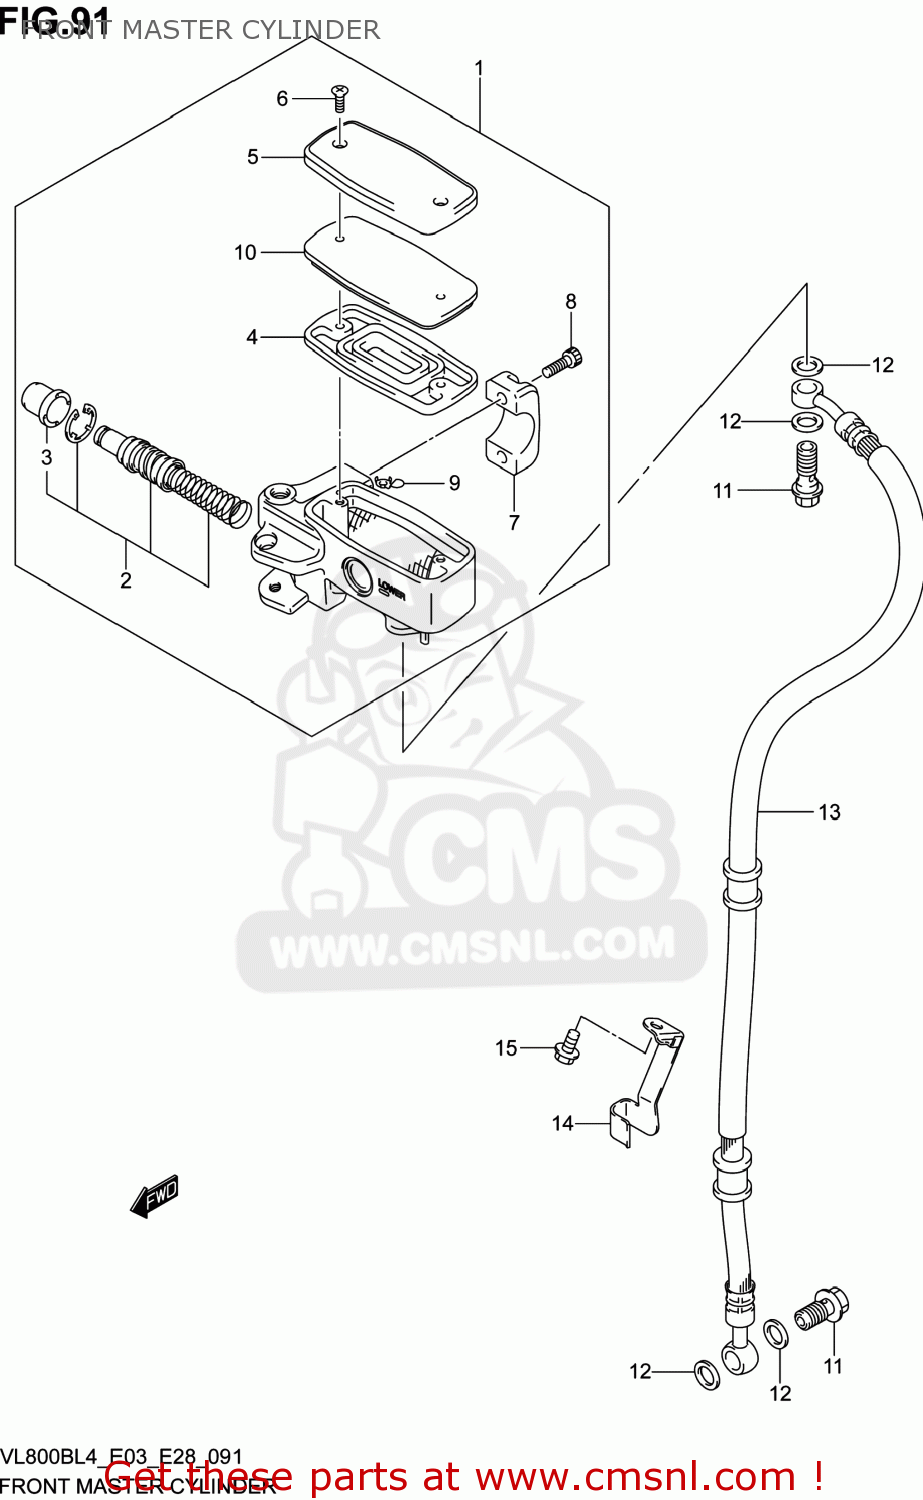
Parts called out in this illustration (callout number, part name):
1	CYLINDER ASSY,FRONT MASTER
2	PISTON/CUP SET
3	BOOT
4	DIAPHRAGM
5	CAP
6	SCREW
7	HOLDER
8	BOLT
9	PROTECTOR
10	PLATE,DIAPHRAGM
11	BOLT UNION
12	WASHER(10X15X1.5)
13	HOSE,FR BRAKE
14	CLAMP,FR BRAKE HOSE UPR
15	BOLT
